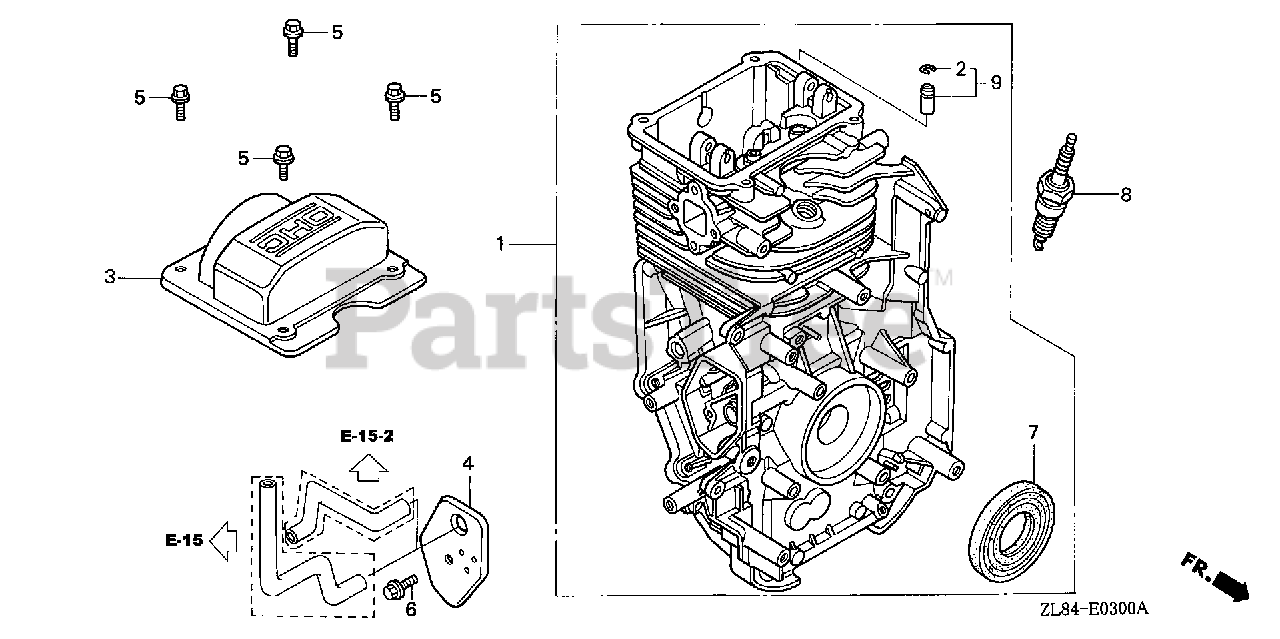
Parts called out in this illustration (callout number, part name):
1	CYLINDER ASSY. (010)
2	CLIP, VALVE GUIDE
3	COVER, HEAD
4	COVER, BREATHER (BREATHER VALVE ASSY.)
5	BOLT, FLANGE (6X12) (CT200)
6	BOLT, FLANGE (6X14)
7	OIL SEAL (25.4X62X6)
8	SPARK PLUG (BPR6ES) (NGK)
9	GUIDE, EX. VALVE (OS)
